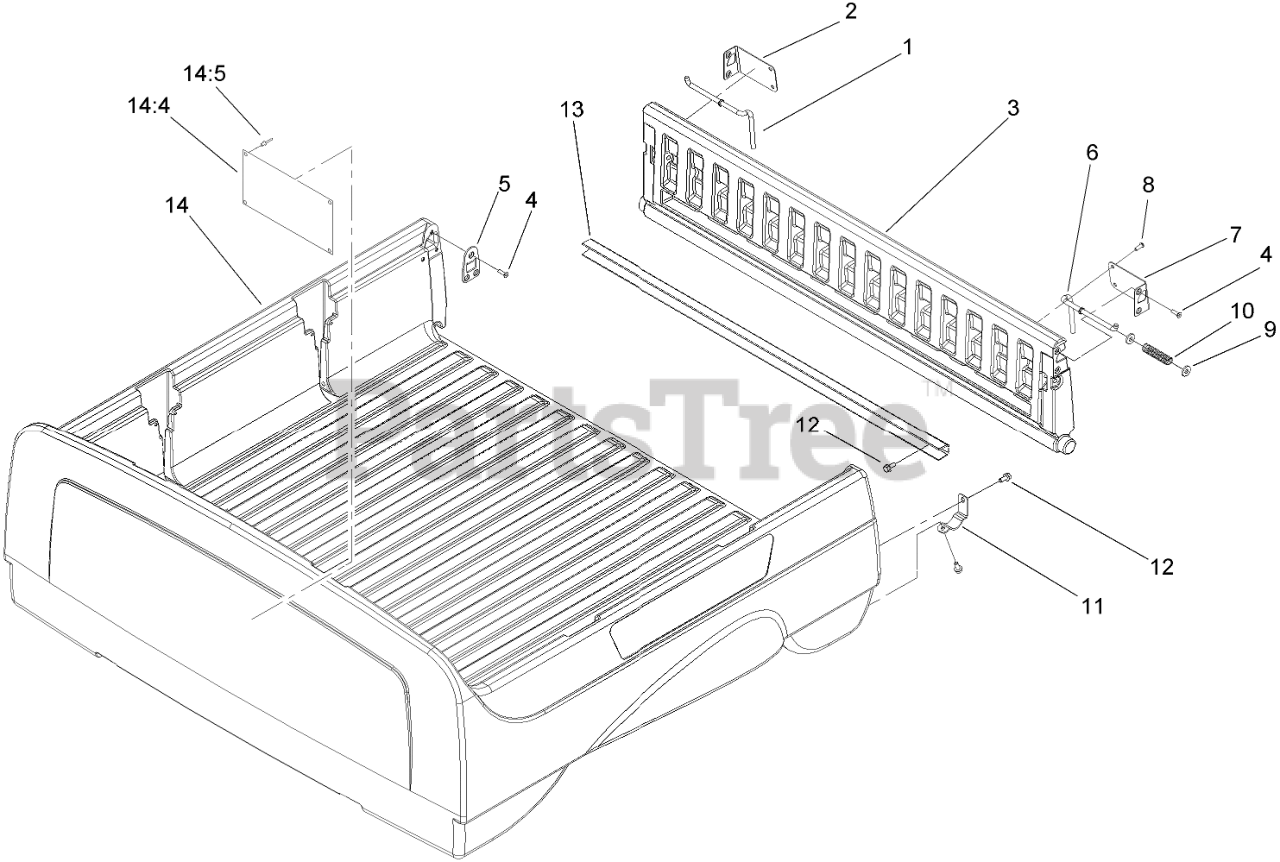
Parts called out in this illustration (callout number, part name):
1	ROD-LATCH, RIGHT
2	BRACKET-TAILGATE LATCH, RIGHT
3	TAILGATE ASM
4	SCREW
5	PLATE-STRIKER
6	ROD-LATCH, LEFT
7	BRACKET-TAILGATE LATCH, LEFT
8	SCREW
9	WASHER-LATCH
10	SPRING
11	BRACKET-PIVOT, TAILGATE
12	SCREW-HHF
13	CHANNEL-TAILGATE
14	Box ASM
14:4	DECAL-NO RIDERS
